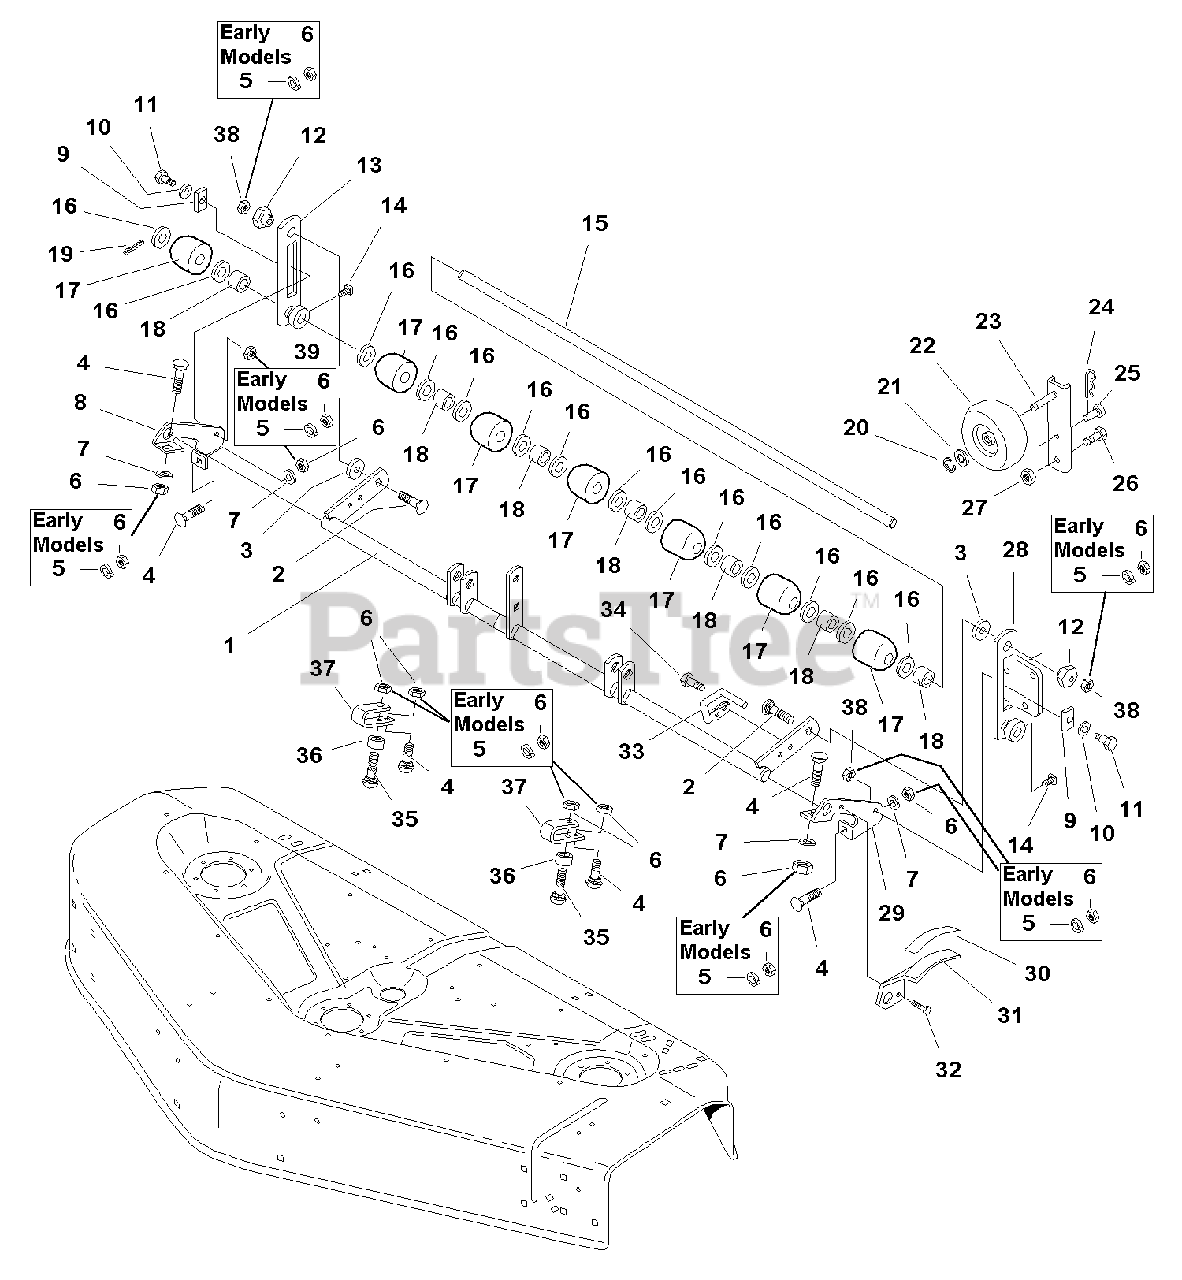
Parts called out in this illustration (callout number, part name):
1	ROCKER SHAFT ASSEMBLY
2	CARRIAGE BOLT, 3/8-16 x 1-3/4
3	WASHER, 3/8
4	CARRIAGE BOLT, 3/8-16 x 1
5	LOCKWASHER, 3/8 (Early Models)
6	NUT, Hex, Full, 3/8-16 (Early Models)
6	NUT, Hex Lock, ESNA, 3/8-16 (Later Models)
7	WASHER, Plain, 3/8
8	BRACKET, Roller, RH
10	WASHER, 1/2 x 1-1/4
11	BOLT, Shoulder, 3/8-16 X 1.34
12	NUT, Hex Adjusting, .99 DIA .687
13	BAR ASSEMBLY, Roller, LH
14	SET SCREW, Square Head, 5/16-18 x 1/2, G8
15	SHAFT, Roller
16	WASHER, 1.0
18	SPACER, Short
19	PIN, Cotter
20	E-RING, 1/2
21	WASHER, Flat, 1/2 x 7/8
22	WHEEL, Slide
23	BAR ASSEMBLY, Wheel
24	HAIRPIN
25	HITCH PIN, 3/8
26	CAPSCREW, Hex Head, 3/8-16 x 1
27	NUT, Hex, Nylon Lock, 3/8-16
28	BAR ASSEMBLY, Roller, RH
29	BRACKET, Roller, LH
30	DECAL, Cutting Height Indicator
31	PLATE, Height Indicator
32	CAPSCREW, Hex Head, Taptite, 1/4-20 x 3/8
33	ROD, Indicator
34	CAPSCREW, Hex Head, Taptite, 5/16-18 x 1/2
35	CARRIAGE BOLT, 3/8-16 x 2-1/4
36	SPACER
38	NUT, Hex Alm Insert Lock, 3/8-16 (Later Models)
